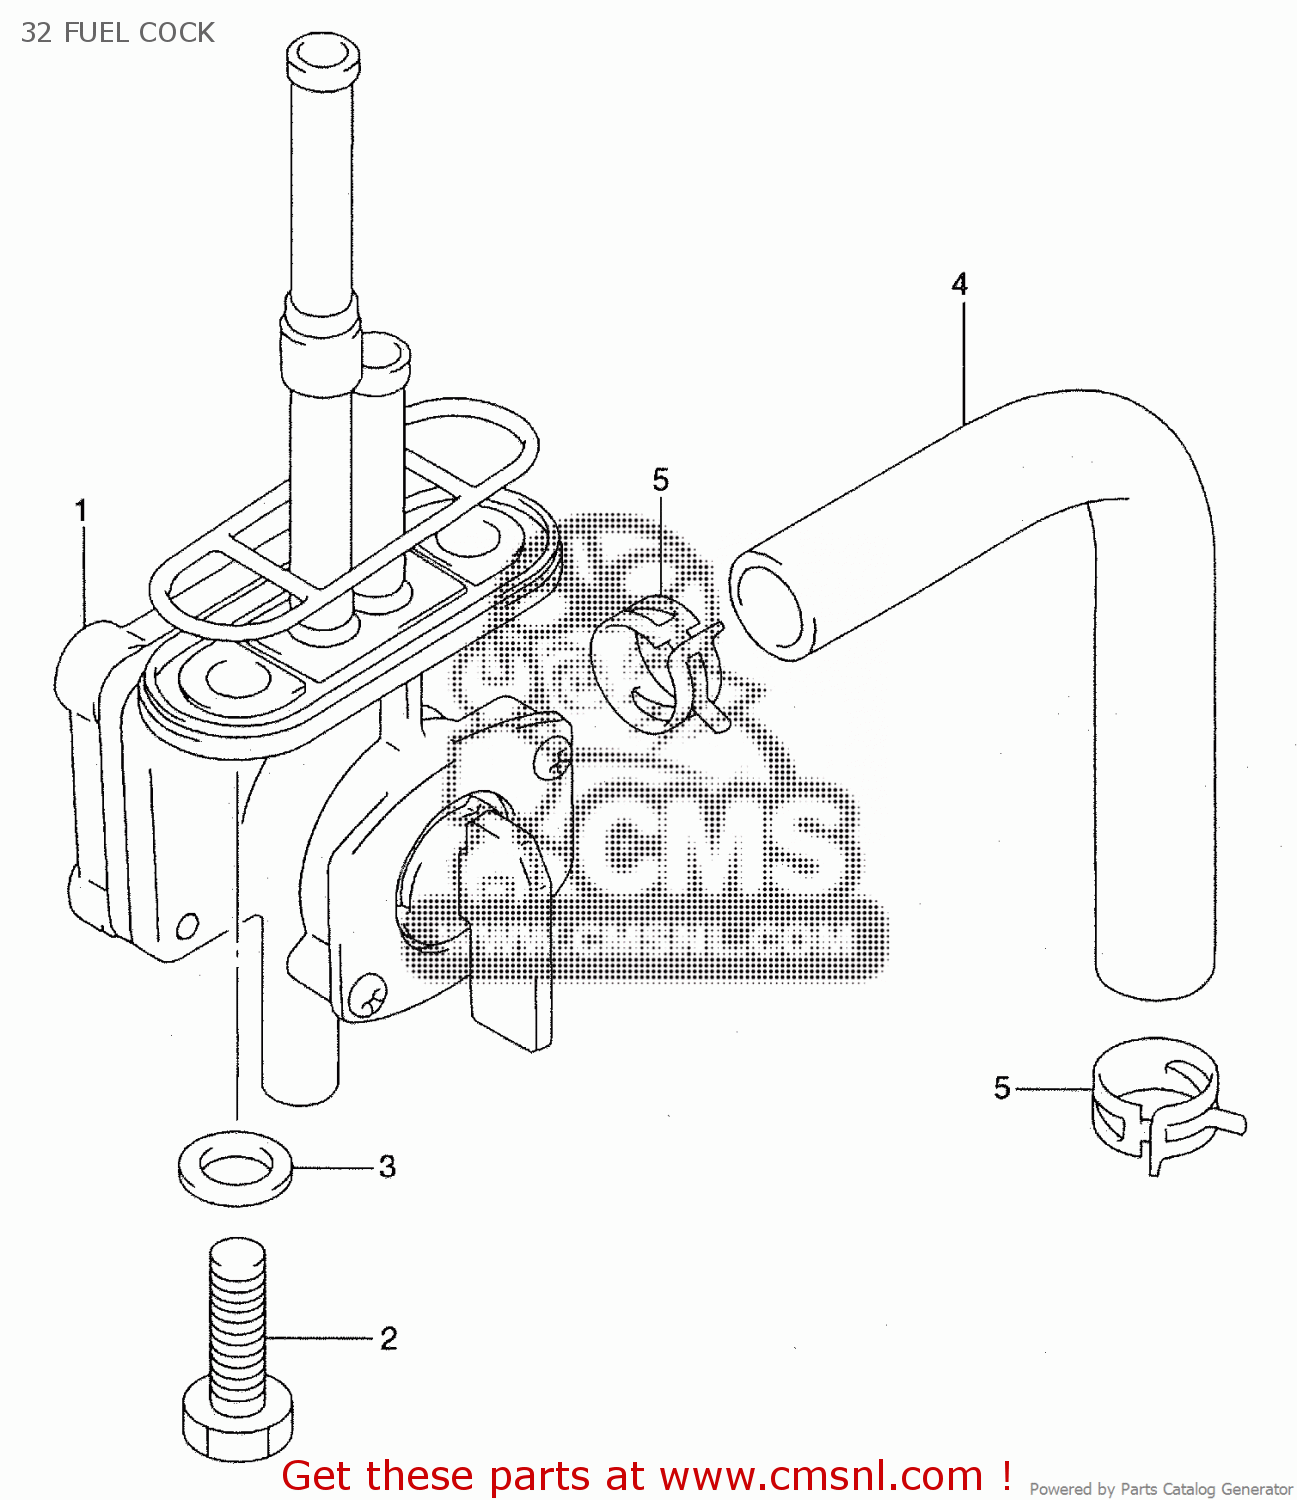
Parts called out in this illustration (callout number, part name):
1	COCK ASSY,FUEL
2	BOLT(6X20)
3	GASKET(6.4X11.5X0.8) (NAS)
4	HOSE(7X12X600)
5	CLIP
